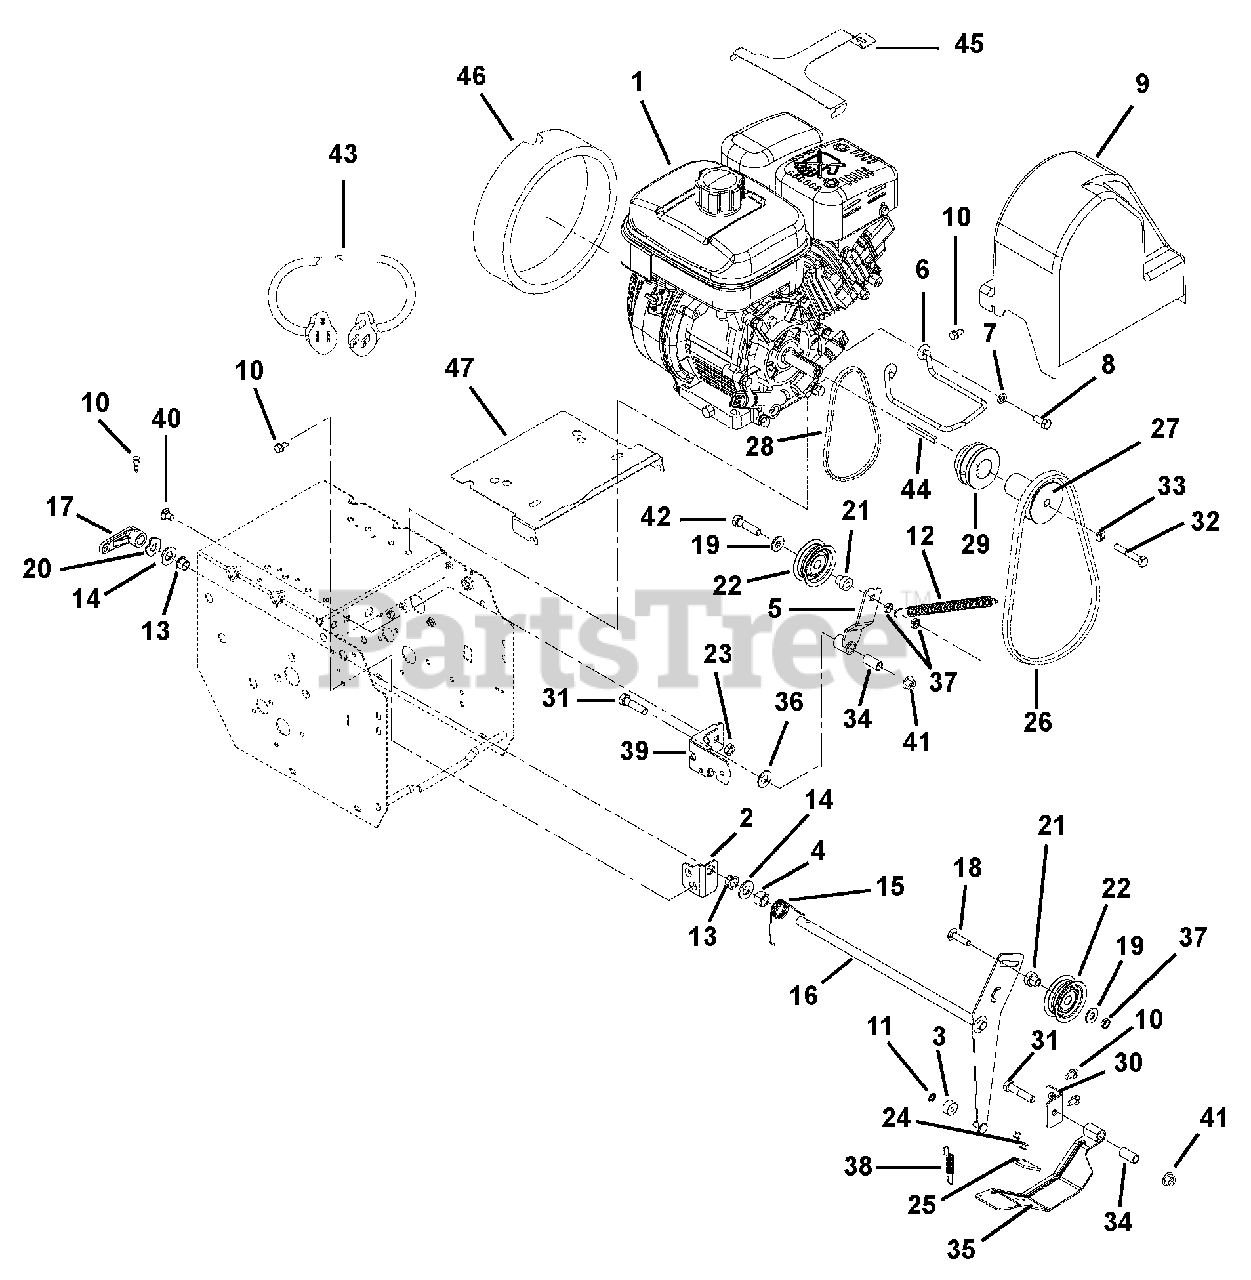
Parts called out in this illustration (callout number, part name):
1	Engine, 6HP Subaru EX17
2	Bracket, Mount- Idler Arm
3	Bushing, Sleeve
4	Bushing, Sleeve
5	Weldment, Traction Idler Arm
6	Belt Finger
7	Washer, Locking .312 x .097 Heavy
8	Bolt, Hex .31-24 x .75 Grade 5
9	Belt Cover
10	Screw, Tapping .25-20 x .50 Hex Washer Head, Thread Rolling
11	Ring, Retaining-External .250 x .010
12	Spring, Extension
13	Bushing, Polyliner .50 Split
14	Washer, Flat Steel .531 x 1.06 x .095
15	Spring, Torsion
16	Weldment, Attachment Idler Arm
17	Arm, Clutch - Attachment
18	Bolt-Round Head Square Short Neck .31-18 x 1.25 Grade 5
19	Washer, Flat Steel .38 x .875 x .083
20	Washer, Wave .50 x .75 x .015, .13 Free Height
21	Spacer, Bearing
22	Idler
23	Nut, Locking-Top-Flange .31-18
24	Rivet-Pop .187 (included with item 35)
25	Brake Pad (included with item 35)
26	V-Belt HA, Attachment
27	Sheave, Attachment Drive
28	V-Belt 3L, Traction
29	Pulley, Traction
30	Bracket, Mount- Brake
31	Bolt, Hex .38-16 x 1.75 Grade 5
32	Bolt, Hex .31-24 x 1.75 Grade 5
33	Washer, Locking .312 x .097 Heavy
34	Bushing, Sleeve
35	Brake Arm W/Pad
36	Washer, Flat-Steel .406 x .812 x .065
37	Nut, Locking Center Jam .31-18
38	Spring, Extension
39	Weldment, Frame Bracket
40	Bolt, Round Head Square Short Neck .31-18 x .62
41	Nut, Top Flange Lock .38-16
42	Bolt, Hex .31-18 x 1.50 Grade 5
43	Cord, Extension 120V
44	Key - SQ, 0.188 x 0.75 x 0.188
45	Guard, Snow - Subaru EX17
46	Foam Cover, Recoil - Subaru
47	Baffle, Water
